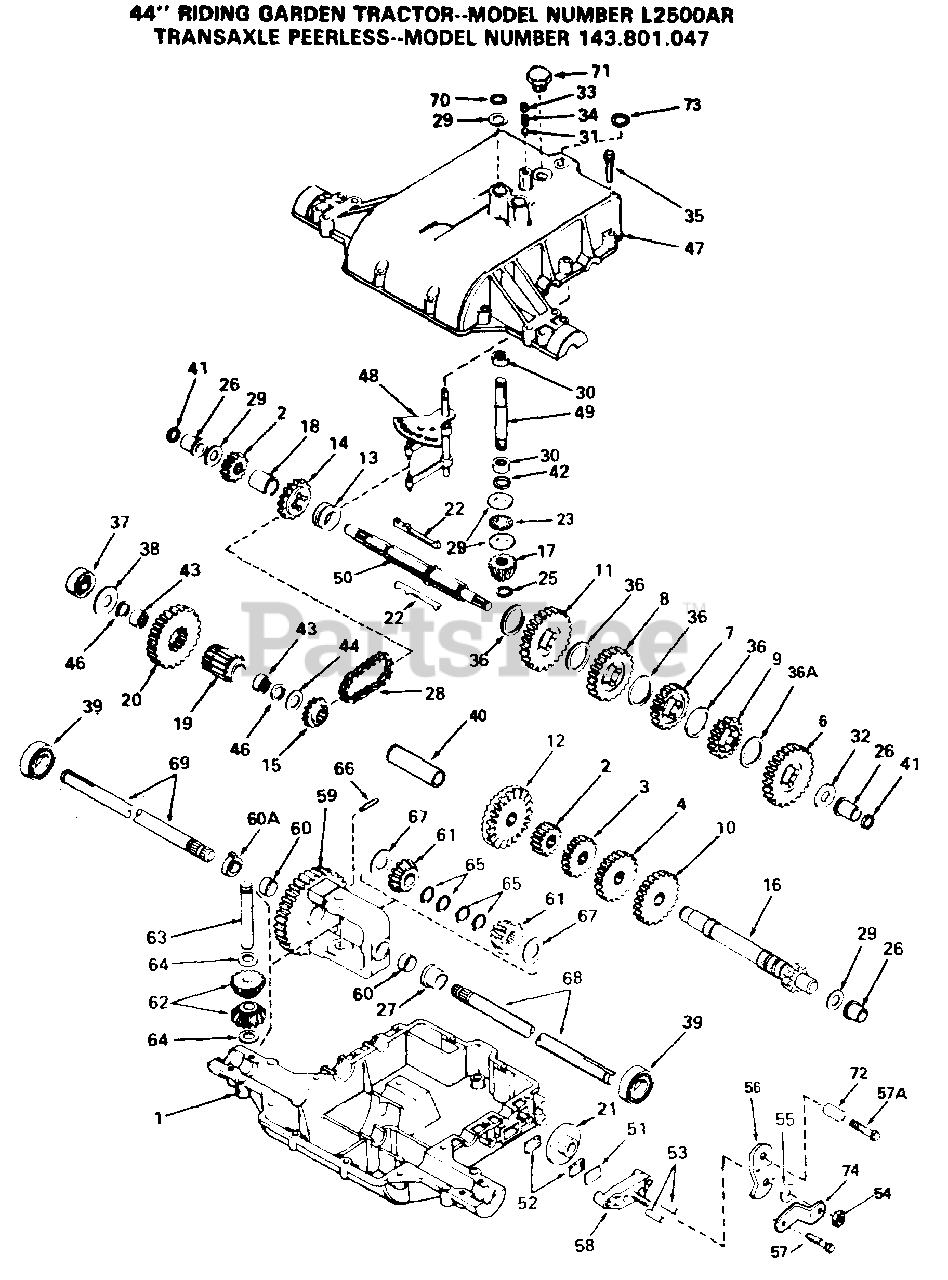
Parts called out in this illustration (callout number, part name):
1	Case, Transfer
2	GEAR, SPUR, 15 TEETH
3	GEAR, SPUR, 20T
4	GEAR, SPUR, 25T
6	GEAR, SPUR (41 TEETH)
7	GEAR, SPUR (25 TEETH)
8	GEAR, SPUR (30 TEETH)
9	GEAR, SPUR, 19 TEETH
10	GEAR, SPUR, 31T
11	GEAR, SPUR (35 TEETH)
12	GEAR, BEVEL, (42 TEETH)
13	COLLAR, SHIFT
14	SPROCKET (18 TEETH)
15	SPROCKET 9T
16	COUNTERSHAFT & GEAR
17	BEVEL PINION, INPUT
19	PINION, OUTPUT
20	GEAR, OUTPUT
21	DISK, BRAKE
22	KEY (4 REQUIRED)
23	THRUST BEARING
25	RETAINING RING
26	BUSHING, FLANGED
27	BUSHING, FLANGED
28	CHAIN, ROLLER
29	WASHER THRUST
30	BEARING, NEEDLE
31	BALL STEEL, 5/16" DIA.
33	SCREW, 3/8-16 X 3/8"
35	SCREW, 1/4-20 X 1-1/4
36	WASHER THRUST
37	BEARING, BALL
38	WASHER, FLAT
39	BEARING BALL
40	SPACER (2-1/4" LONG)
41	SEAL, SQUARE CUT
43	BEARING, NEEDLE
44	WASHER, FLAT
46	SEAL, SQUARE CUT
47	COVER, TRANSAXLE
48	ROD & FORK ASSY., SHIFT
49	SHAFT, INPUT
50	SHAFT, BRAKE
51	PLATE BRAKE PAD
54	LOCKNUT 5/16-24
55	WASHER, FLAT
56	LEVER, BRAKE
57	SCREW, 1/4-20 X 1-1/4
57A	SCREW FLNG HEX 1/4-20 X 2-1/4
58	HOLDER BRAKE PAD
59	GEAR ASSY DIFFERENTIAL (INCL. 2 OF #60)
61	GEAR, BEVEL
62	PINION, BEVEL
63	PINE, DRIVE
64	WASHER, THRUST
65	RING RETAINER
68	AXLE (15-1/8" LONG)
69	AXLE (13-1/4" LONG)
70	RING, RETAINER
71	PLUG, THRDED, 9/16-18
73	SEAL SQUARE CUT
74	BRKT BRAKE LEVER
